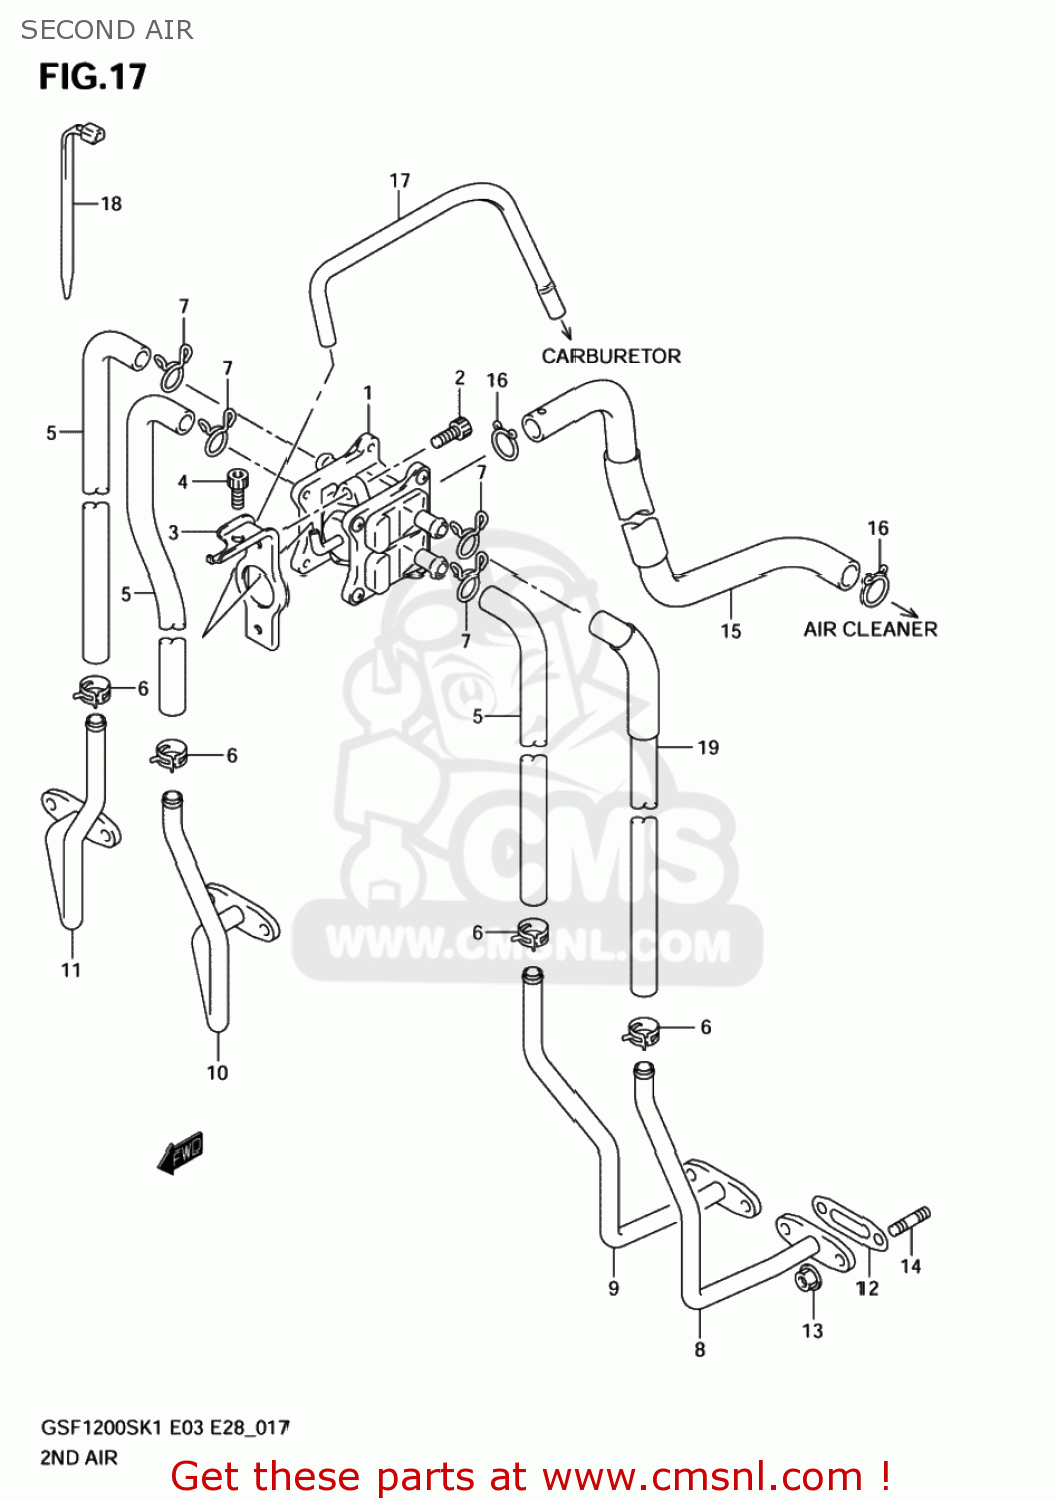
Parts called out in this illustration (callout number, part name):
1	VALVE ASSY,2ND AIR
2	BOLT,OIL FILLE
3	BRACKET,2ND AIR
4	BOLT
5	HOSE,2ND AIR VALVE NO.1
6	CLIP
7	CLIP
8	PIPE,2ND AIR NO.1
9	PIPE,2ND AIR NO.2
10	PIPE,2ND AIR NO.3
11	PIPE,2ND AIR NO.4
12	GASKET,2ND AIR PIPE (NAS)
13	NUT
14	STUD BOLT
15	HOSE,2ND AIR CLEANER
16	CLIP
17	HOSE(4X7X600)
18	CLAMP(L:165)
19	HOSE,2ND AIR VALVE NO.1
